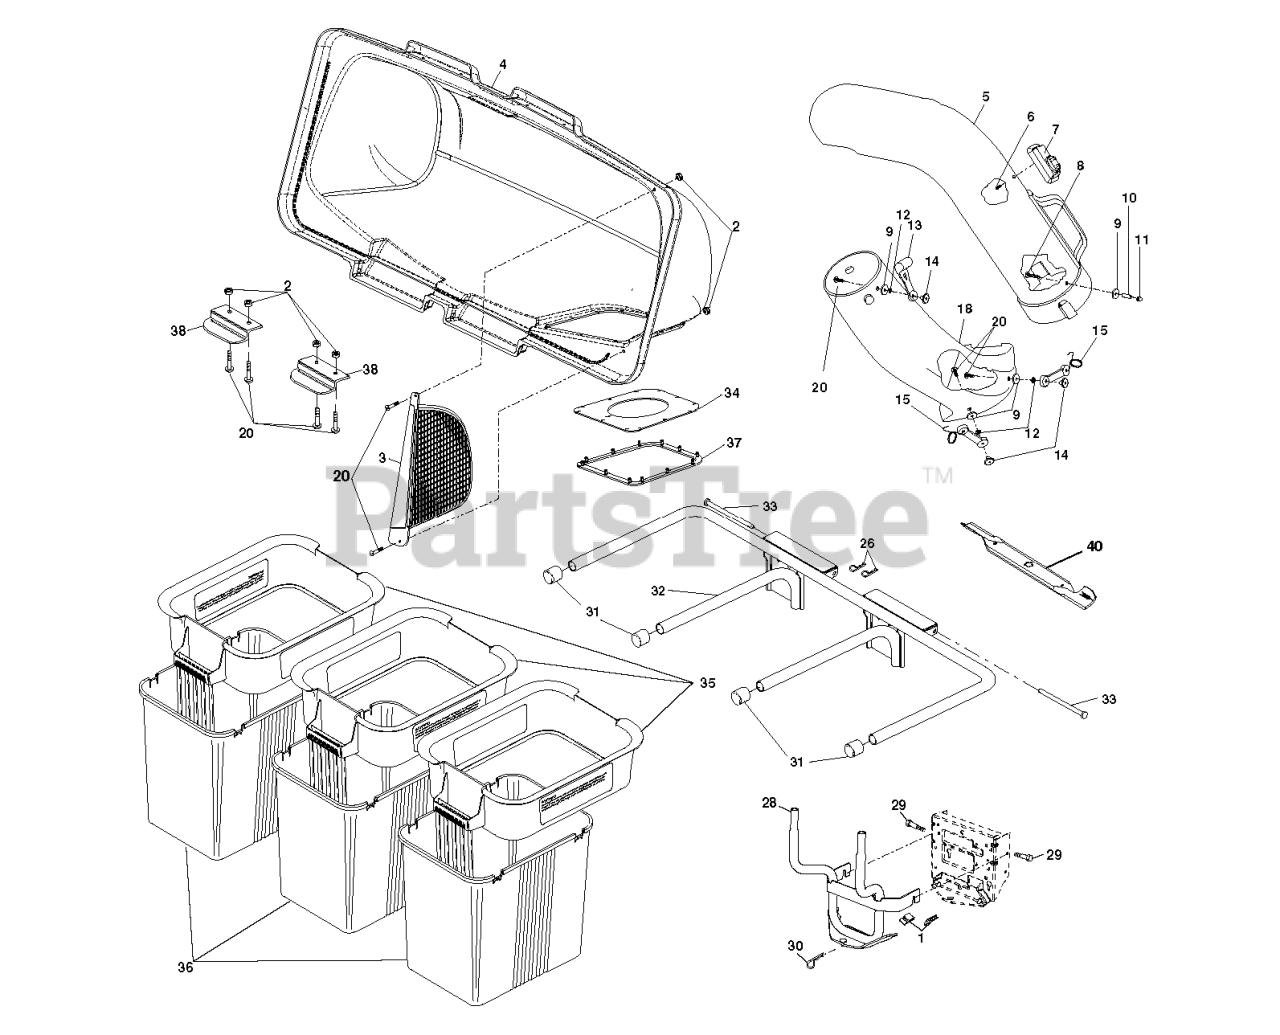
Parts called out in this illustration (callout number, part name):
1	ADAPTER.LT.3-BIN.QA.TEX
3	SCREEN.COVER.BAGGER
4	COVER.ASM.3BIN.GENERIC.
5	CHUTE.UPPER.42"
7	INDICATOR ASM BAG
8	SCREW
9	RP STEEL WASHER
11	NUT
12	LOCKWASHER #10
13	LATCH.HOOD.
14	WELDNUT
15	LATCH ASSY
18	LOWER CHUTE FOR 38" BAGGER
20	SCREW
26	RETAINER-SPRNG RB
28	BRACKET.BAGGER.3-BIN.BLACK
29	BOLT.SHOULDER
30	SPRING.RETAINER.YELLOW.ZINC
31	PLUG, TUBING END
32	BAGGER.ASM.FRAME.3BIN.BLACK
33	BAGGER.HINGE.PIN
34	SEAL.BAGGER.TOP.3-BIN.BLK
35	CONTAINER TOP
36	CONTAINER BOTTOM
37	GASKET.COVER.BAGGER
38	LATCH CER38
40	BLADE.HI.LIFT.38"
